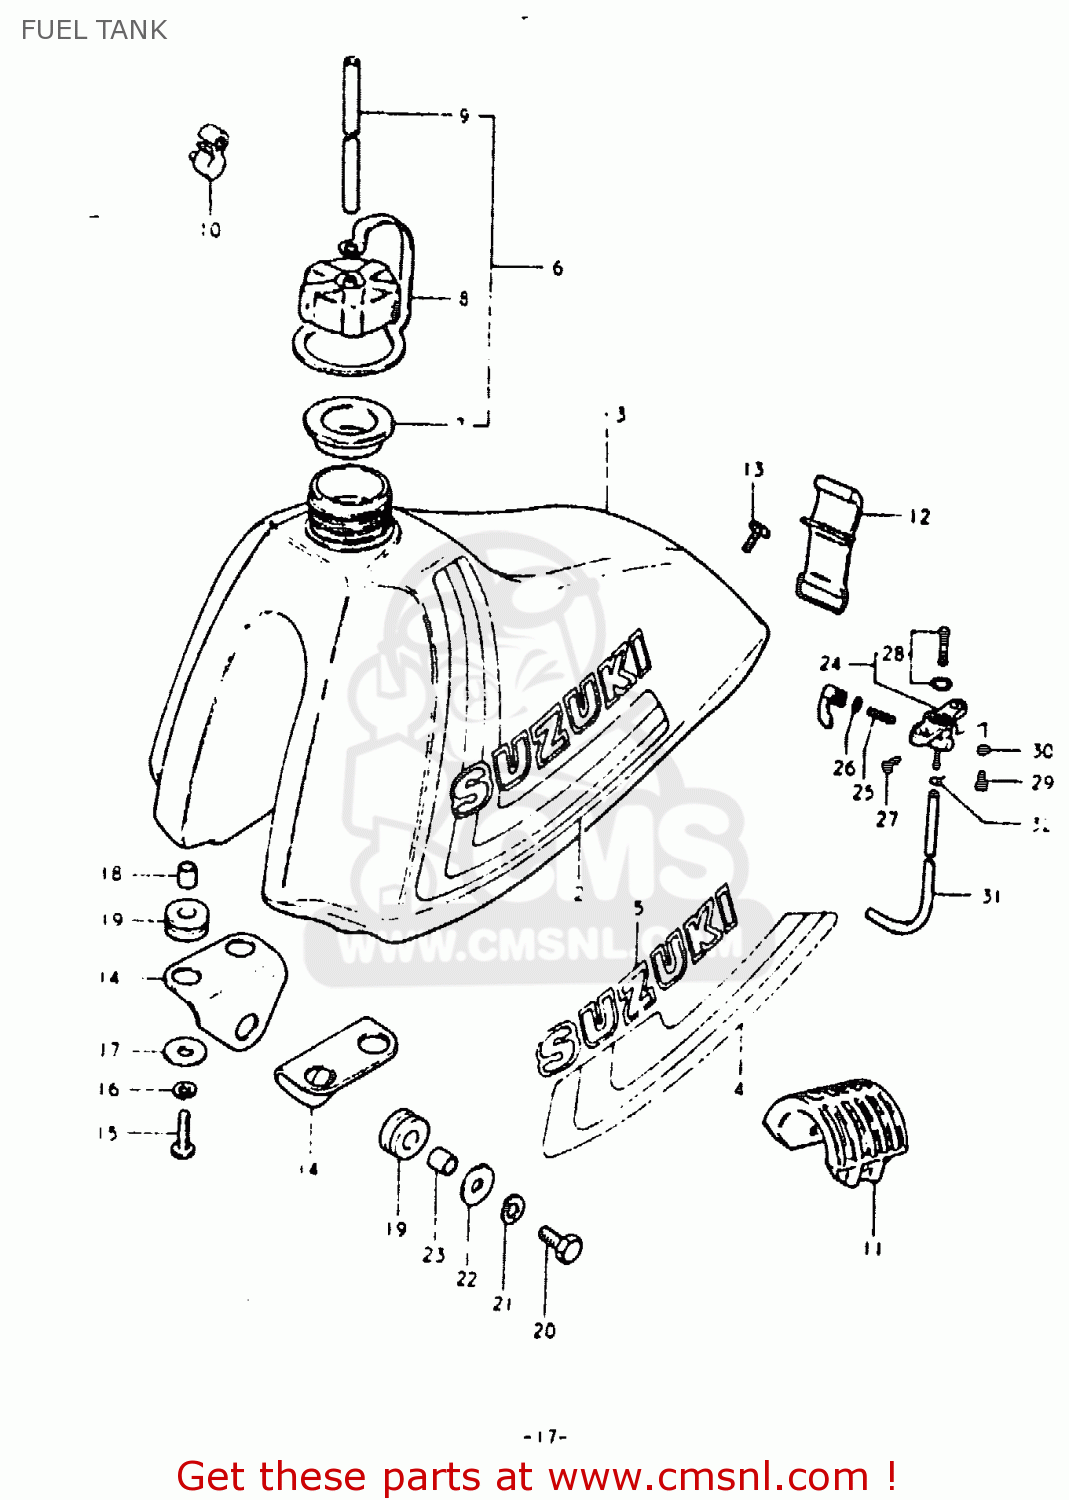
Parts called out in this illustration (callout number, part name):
3	TANK ASSEMBLY,FUEL
4	TAPE SET,FUEL TANK
5	EMBLEM
6	CAP SET,FUEL TANK
7	GASKET,FUEL TANK CAP (NAS)
8	HOSE
9	BAND,FUEL TANK CAP
10	CLAMP,FUEL TANK BREATHER HOSE
11	CUSHION,FUEL TANK
12	BAND
13	SCREW(6X18)
14	BRACKET,FUEL TANK,LOWER
15	SCREW
16	LOCK WASHER
17	WASHER (6.5X24X1.6)
18	SPACER(6.8X12X11)
19	CUSHION
20	BOLT
21	LOCK WASHER
22	WASHER (8.2X24X1.6)
23	SPACER (8.8X12X11)
24	COCK ASSEMBLY,FUEL
25	SPRING,FUEL COCK VALUE
26	O RING,LEVER
27	SCREW
28	FILTER SET FUEL
29	SCREW
30	LOCK WASHER
31	HOSE
32	CLAMP
